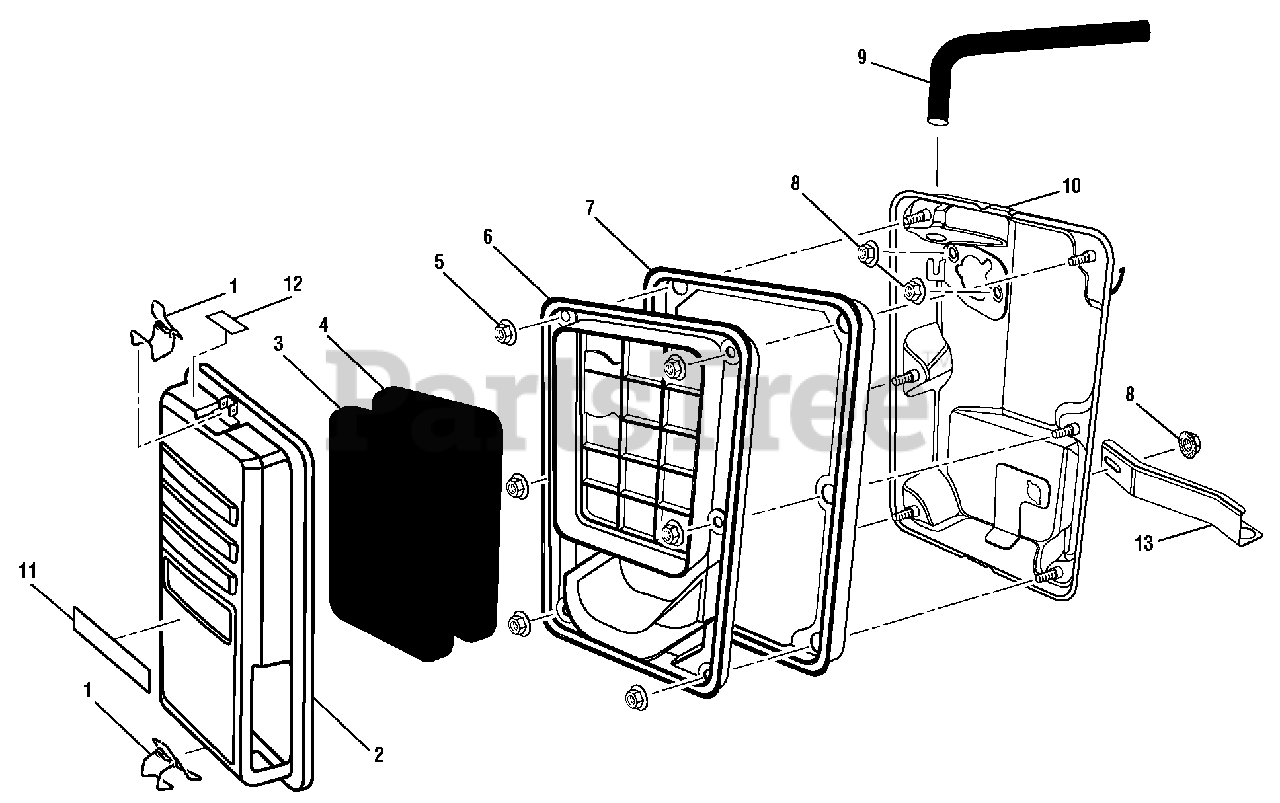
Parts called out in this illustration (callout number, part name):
1	Air Cleaner Cover Hinge
2	Air Cleaner Cover Assembly
3	Pre-filter
4	Air Filter Element
5	Nut (M5, Flange Nut)
6	Filter Element Retainer
7	Air Cleaner Gasket
8	Nut (M6, Flange Nut)
9	Breather Tube
10	Air Cleaner Support
11	Starting Instruction Label
12	Choke Label
13	Air Cleaner Bracket
